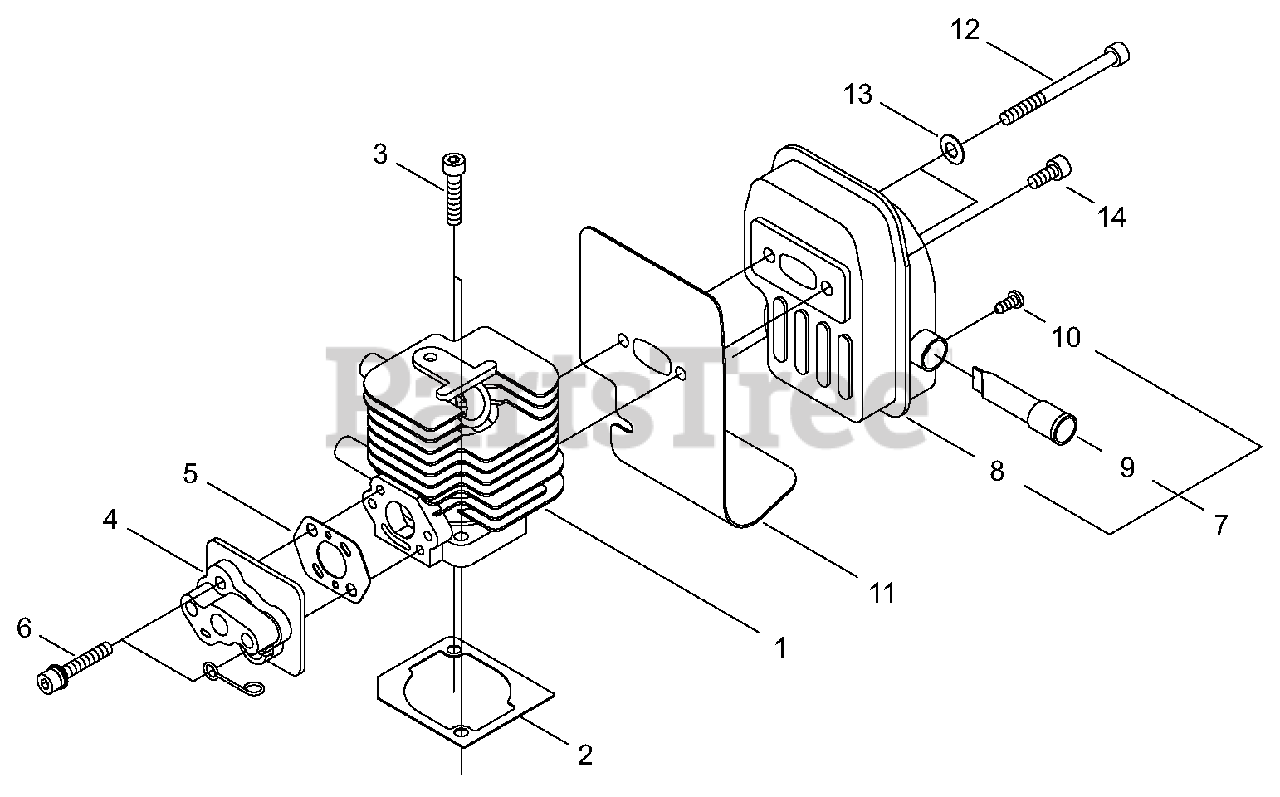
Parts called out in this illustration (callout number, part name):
1	CYLINDER
2	GASKET, CYLINDER
3	SCREW - 5X25
4	INSULATOR, INTAKE
5	GASKET, INTAKE
6	SCREW - 5X30
7	MUFFLER ASSY
8	MUFFLER
9	SCREEN, SPARK ARRESTOR
10	SCREW - 3X6
11	SHIELD, EXHAUST
12	SCREW - 5X50
13	WASHER - 5
14	SCREW - 5X12
